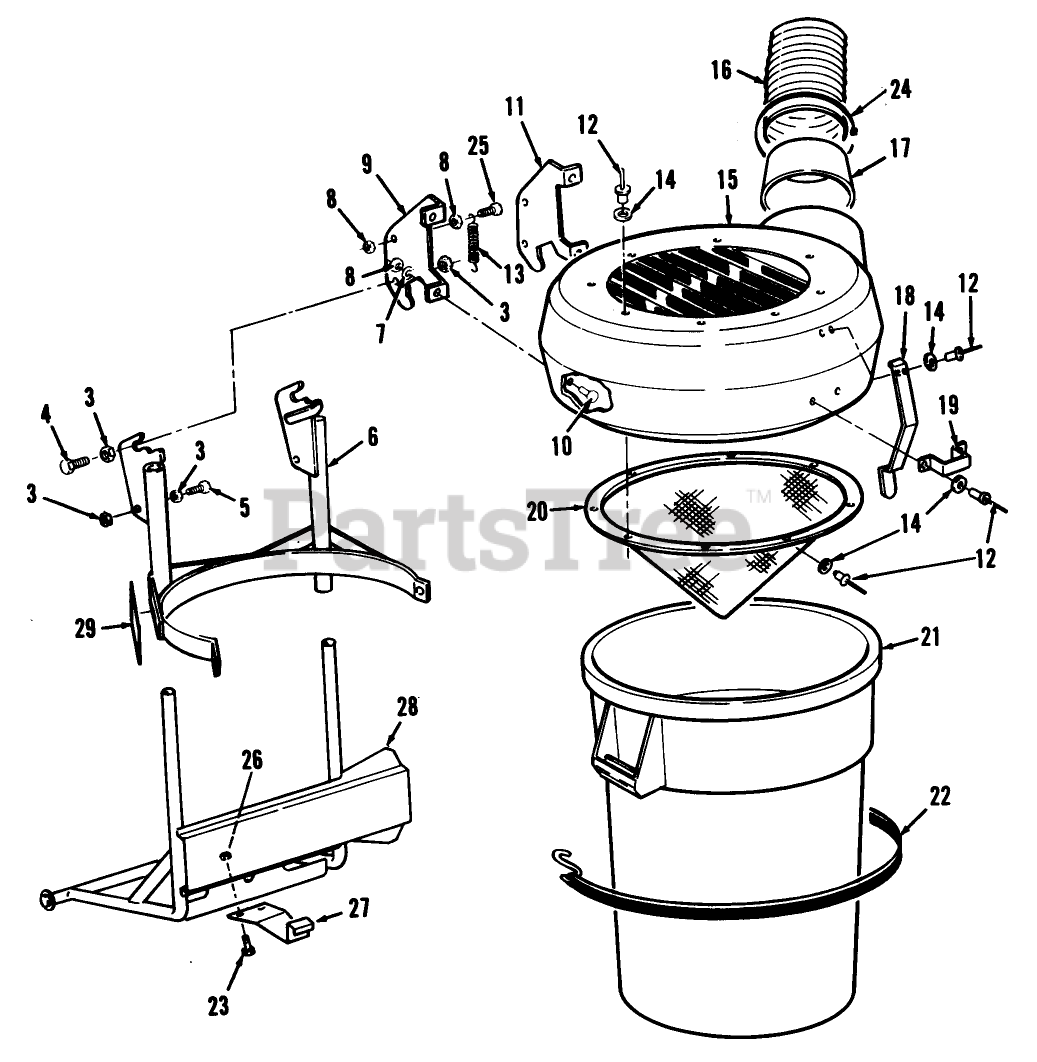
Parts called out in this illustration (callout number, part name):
3	NUT-HEX
4	SCREW-HH
5	SCREW-HH
7	WASHER-PLAIN
8	NUT-LOCK, NI
9	LH TOP BRACKET *B
10	SCREW-HH
12	RIVET-POP
13	SPRING-EXTENSION
15	TOP-CANISTER
17	SEAL ASSEMBLY *NP
19	BRACKET *B
22	STRAP *B
23	SCREW-HH
25	SCREW-HH
26	NUT-HEX
27	BRKT-CANISTER SUP *B
28	WLDMT-BAGGER RODS *B
29	DECAL-DANGER
